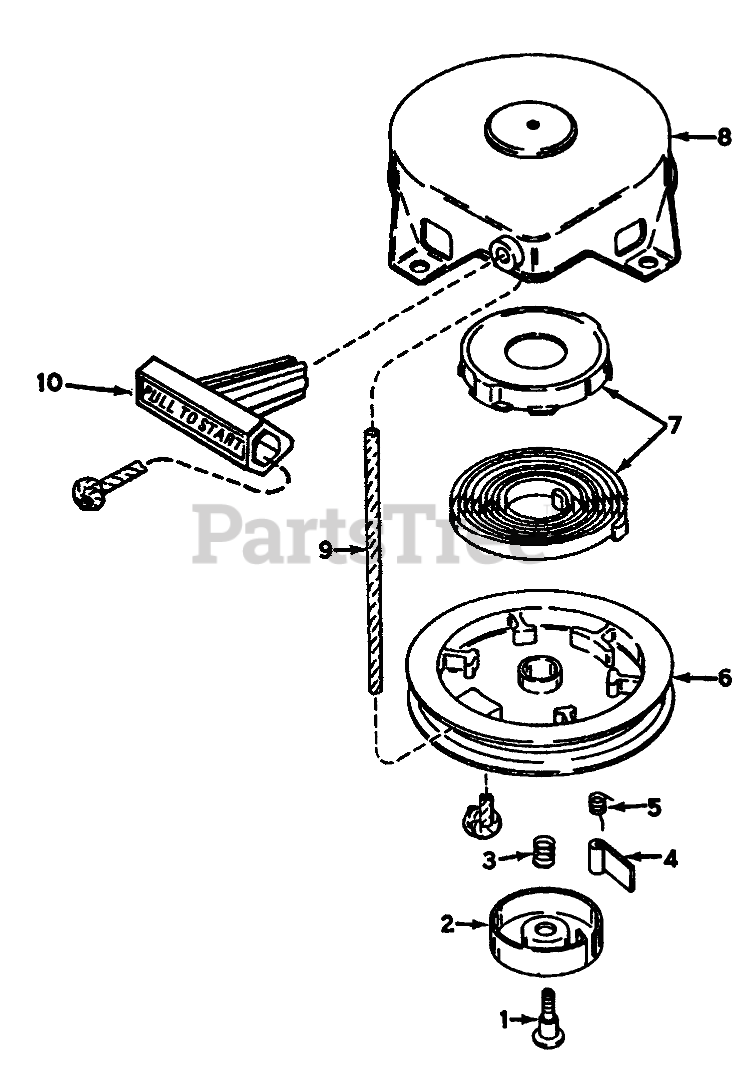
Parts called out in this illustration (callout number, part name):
2	Retainer
3	Spring-Brake
4	Dog-Starter
5	Spring-Dog
7	Spring & Keeper Assy
8	Housing-Starter
9	Rope-Starter (98 cut to length)
10	Handle-Starter
